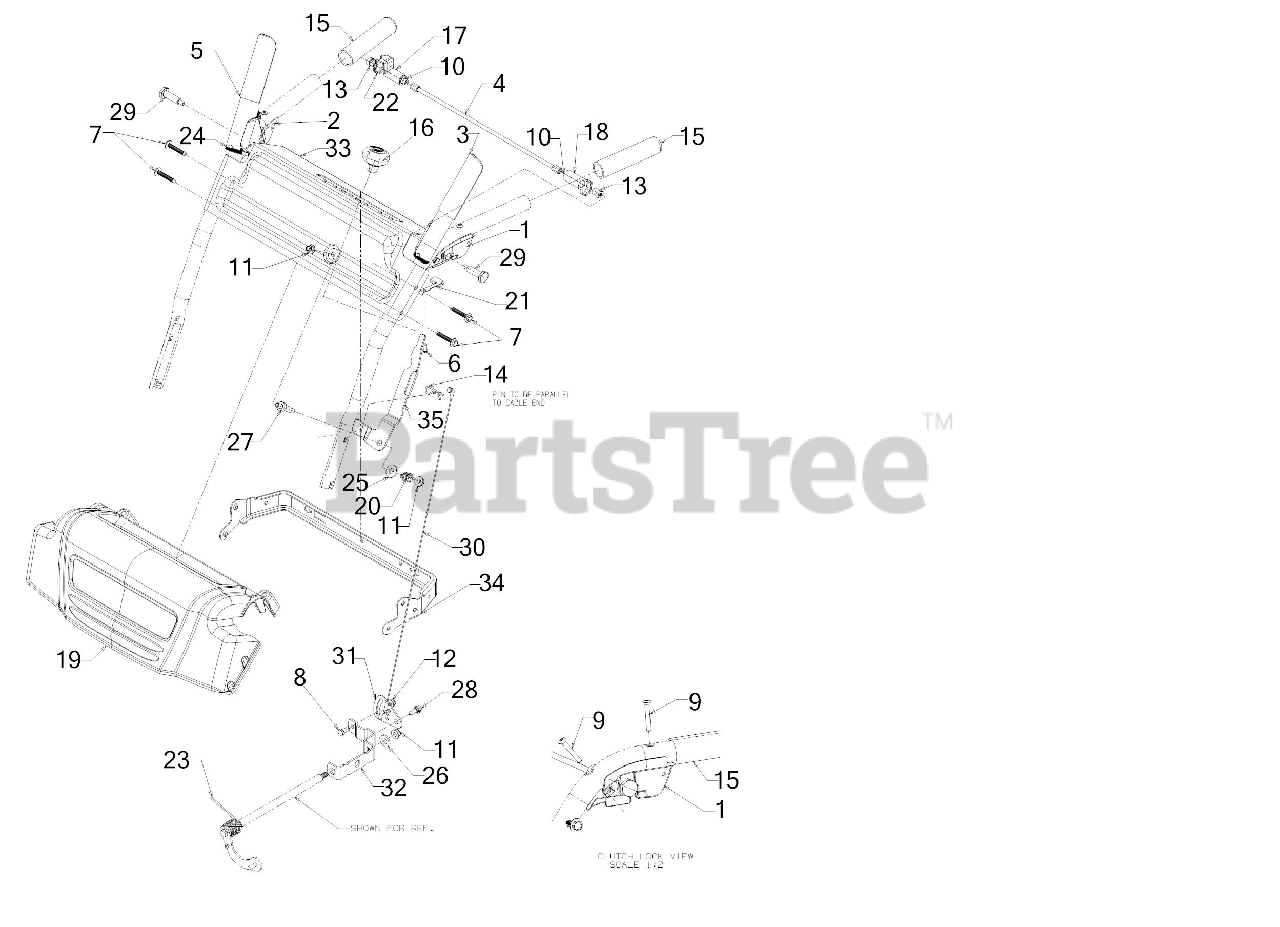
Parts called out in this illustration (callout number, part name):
1	CLUTCH LOCK HANDLE ASSEMBLY (LH)
2	CLUTCH LOCK HANDLE ASSEMBLY (RH)
3	HANDLE ASSEMBLY (LH)
4	PIVOT ROD
5	ENGAGEMENT HANDLE ASSEMBLY (RH) (RED)
6	SCREW #8-16 x .50
7	SCREW 1/4-20 x 1.625
8	SCREW 1/4-20 x .620 GR5
9	SCREW #10-24 x 1.375
10	SCREW 1/4-20 x .50
11	FLANGE LOCK NUT 5/16-18
12	FLANGE LOCK NUT
13	HEX NUT W/PATCH
14	INTERNAL COTTER PIN
16	SHIFT KNOB
17	LOCK PLATE
18	CLUTCH LOCK CAM
19	PANEL HANDLE COVER
20	COMPRESSION SPRING
21	CLUTCH SPRING
22	TORSION SPRING
23	TORSION SPRING
24	RUBBER BUMPER
25	FLAT WASHER .385X.870X.090
26	FLAT WASHER
27	SHOULDER BOLT
28	SHOULDER SCREW
29	SHOULDER SCREW .437 x 1.345 1/4-20
30	SPEED SELECTOR CABLE (STEEL)
31	PIVOT BRACKET
32	SHIFT SPEED BRACKET
33	HANDLE PANEL-STEEL W/O CUTOUT
34	HANDLE SUPPORT BRACKET
35	SPEED SHIFT LEVER
